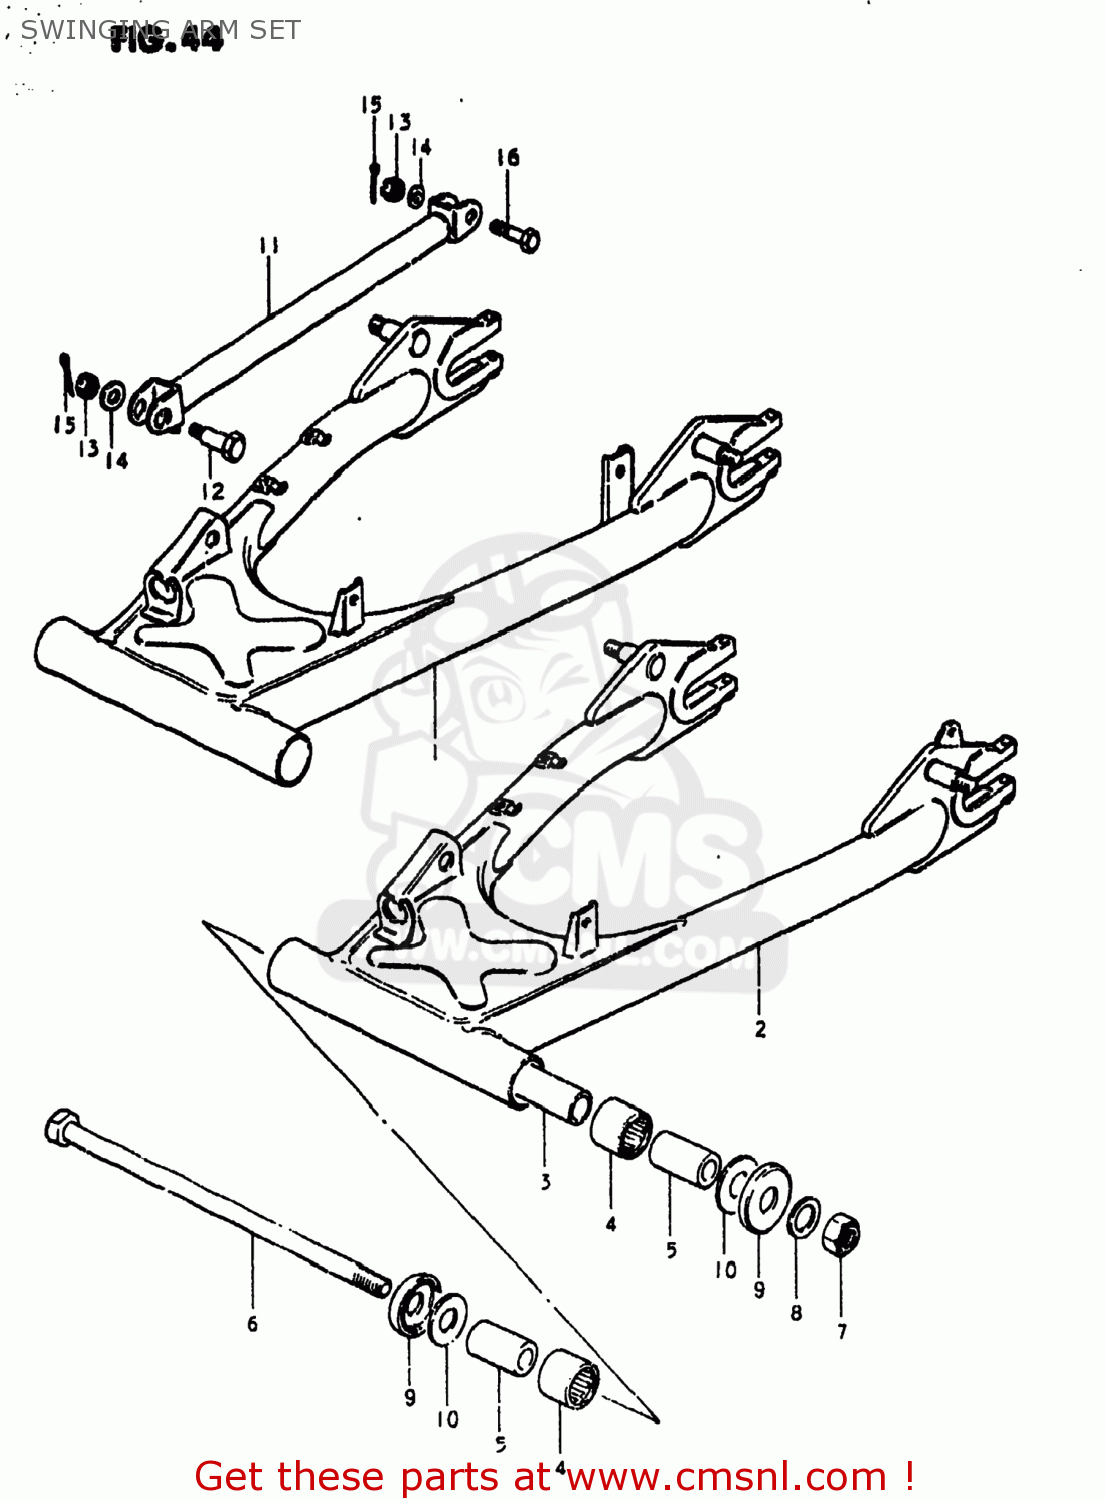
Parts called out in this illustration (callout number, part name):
1	SWING ARM ASSEMBLY,REAR
2	SWING ARM ASSEMBLY,REAR
3	SPACER,RR SWGARM PIVOT CTR
4	OIL SEAL
5	SPACER,RR SWGARM PIVOT
6	SHAFT,REAR SWING ARM
7	NUT 14MM
8	WASHER
9	CVR,RR SWGARM DUST SEAL(OD:40)
10	WASHER(14.2X34X1)
11	LINK,REAR TORQUE
12	BOLT
13	NUT
14	WASHER
15	PIN 20X20
16	BOLT(10X39)
